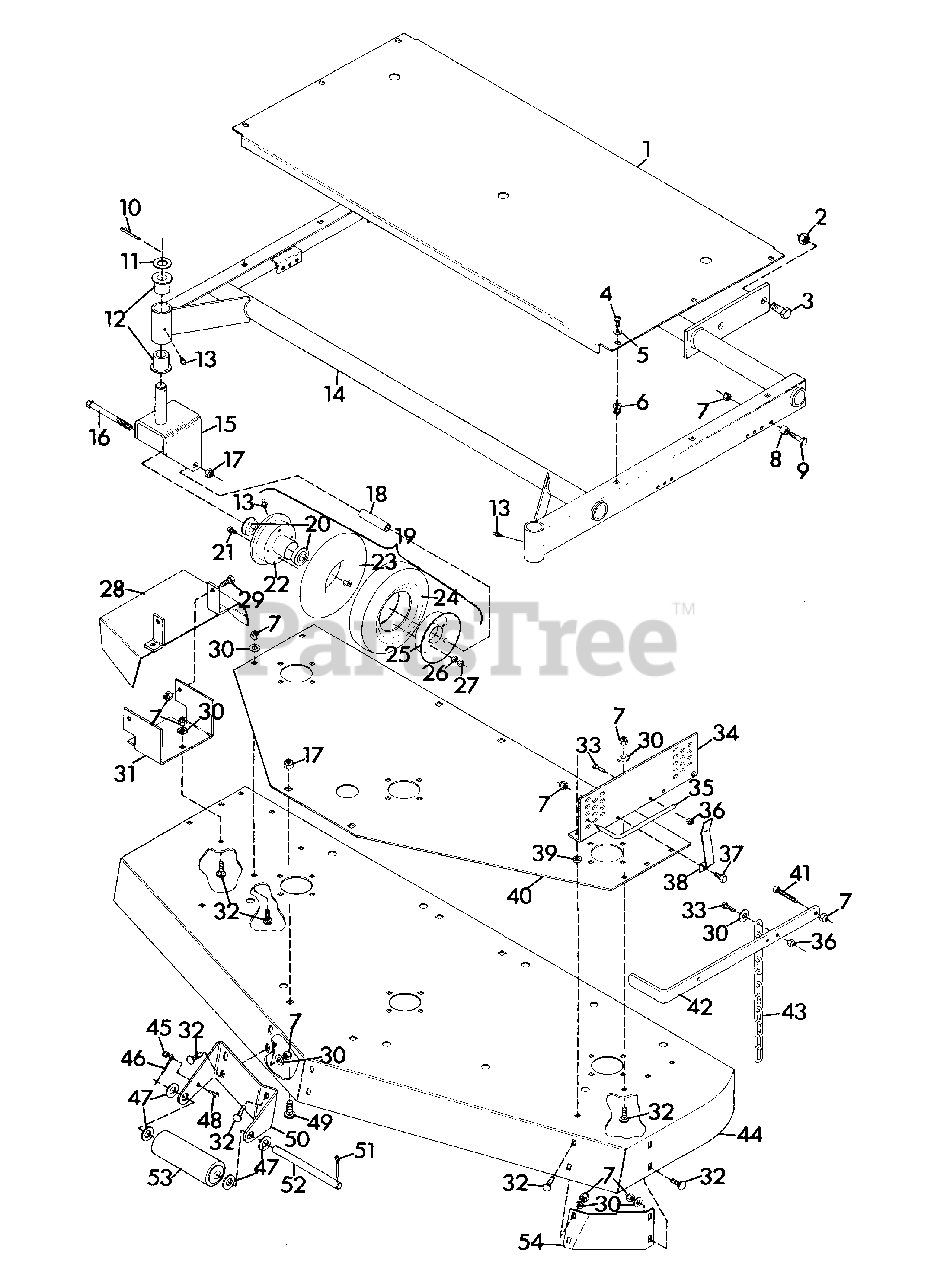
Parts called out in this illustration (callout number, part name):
1	GUARD, BELT PRO-60
2	NUT, LOCK 5/8-11
3	BOLT, HEX 5/8-11X1.50
4	SCREW, MACH. 1/4-20X.625 RD HD
5	WASHER, FLAT .281X.625X.065
6	GROMMET, PLASTIC
7	NUT, LOCK 3/8-16
8	BUSHING .391X.622X.670
9	BOLT, HEX 3/8-16X1.50
10	PIN, COTTER .187X1.62
11	RACE, BEARING THRUST
12	BUSHING, PIVOT
13	FITTING, LUBE 1/4-28
14	WELDMENT, MOWER FRAME
15	WELDMENT, CASTER FORK
16	BOLT, HEX 1/2-13X5.00
17	NUT, LOCK 1/2-13
18	BUSHING, WHEEL .520X.750X3.312
19	WHEEL, GAUGE
20	BEARING, GAUGE WHEEL
21	BOLT, HEX 3/8-24X.75
22	WHEEL, HALF
23	TUBE, INNER
24	TIRE, GAUGE WHEEL
25	WHEEL, HALF PLAIN
26	WASHER, LOCK 3/8 SP HEAVY
27	NUT, HEX 3/8-24
28	WELDMENT, DISCHARGE CHUTE
29	BOLT, HEX 3/8-16X1.00
30	WASHER, FLAT .406X.812X.065
31	BRACKET, DISCHARGE
32	BOLT, 3/8-16X1.00 RD HD SQ NK
33	BOLT, HEX 5/16-18X1.00
34	BRACKET, MOWER SUPPORT L.H.
34	BRACKET, MOWER SUPPORT R.H.
35	PIN, MOWER LOCKING
36	NUT, LOCK 5/16-18
37	BOLT, HEX 3/8-16X.75
38	SPRING, PIN
39	SPACER, IDLER .406X.750X.188
40	PLATE, SUPPORT
41	BOLT, HEX 3/8-16X2.00
42	BAR, LIFT
43	CHAIN, HEIGHT ADJUSTMENT
44	WELDMENT, 60" MOWER
45	NUT, HEX 1/4-20
46	PIN, COTTER .25X2.0
47	WASHER, FLAT .656X1.312X.095
48	BOLT, HEX 1/4-20X.75
49	BOLT, 1/2-13X1.00 RD HD SQ NK
50	BRACKET, ROLLER FRONT
51	PIN, COTTER .25X1.0
52	SHAFT, CENTER ROLLER
53	ROLLER, GAUGE
54	BAFFLE, FRONT
NS	DECAL, DANGER HAND
NS	DECAL, DANGER FOOT
NS	DECAL, WARNING EYE
NS	STRIPE
NS	DECAL, LUBE
NS	DECAL, GRAVELY LOGO
NS	DECAL, PRO-60
